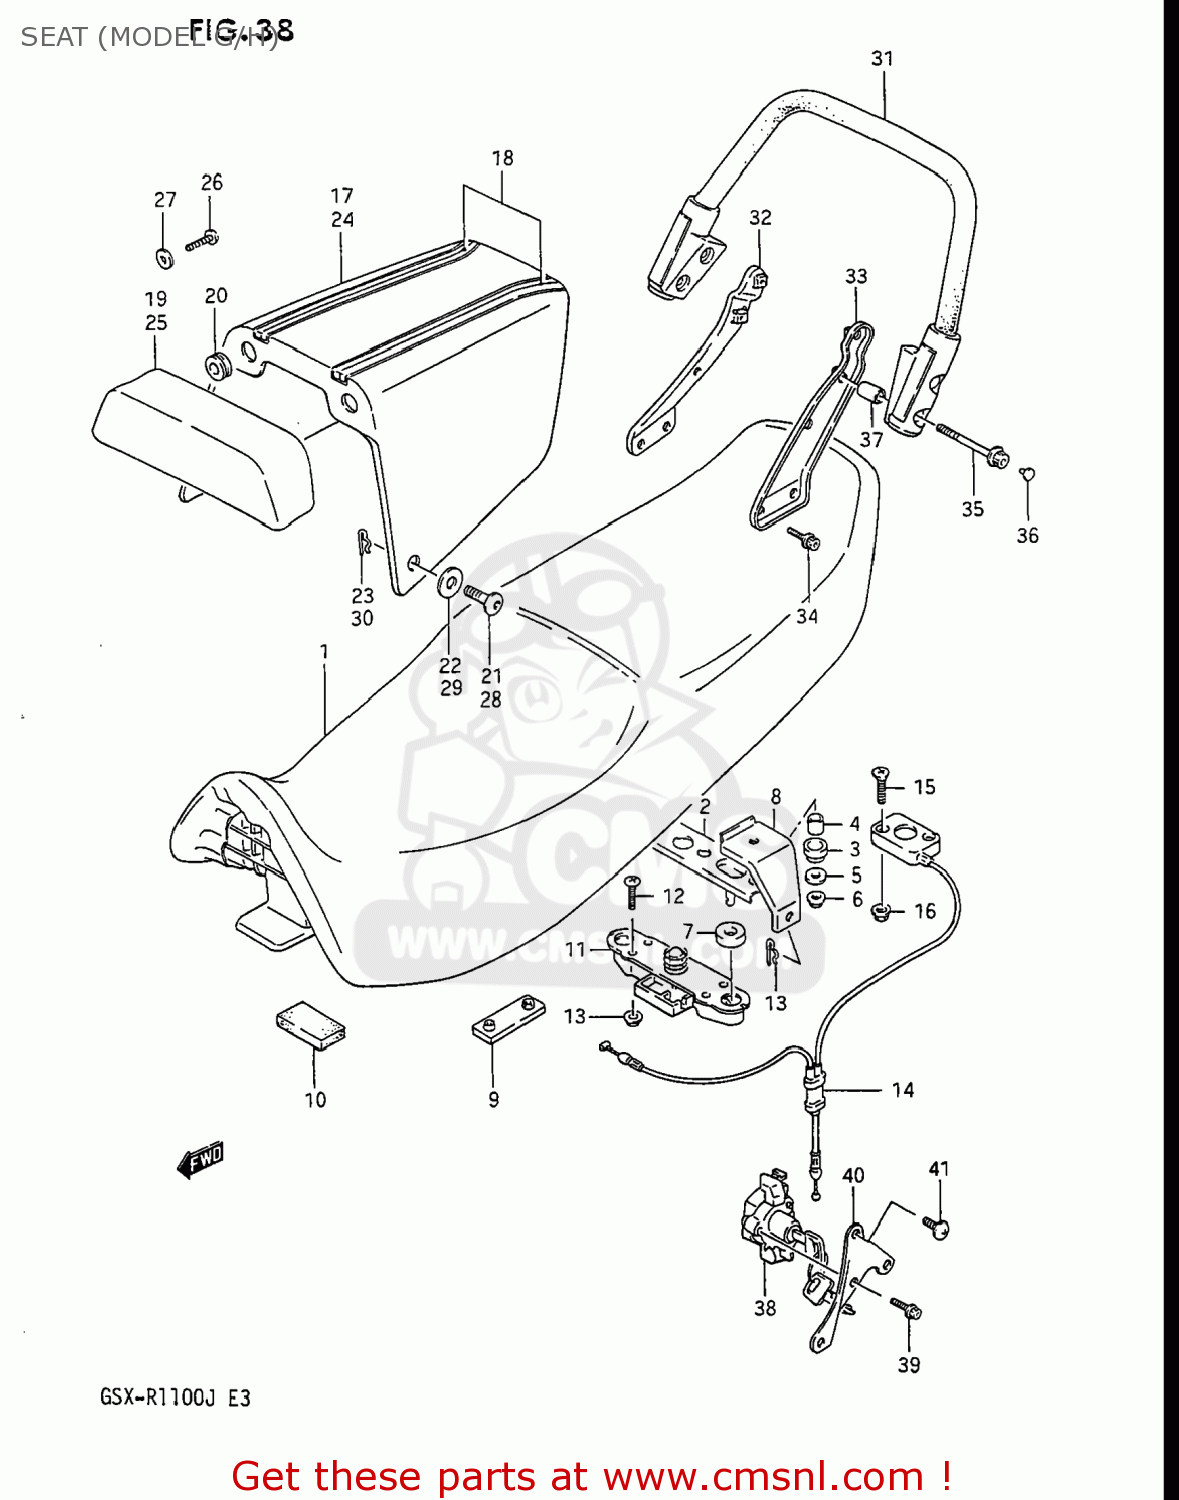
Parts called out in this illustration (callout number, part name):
1	SEAT ASSEMBLY
2	STRIKER,SEAT LOCK
3	CUSHION
4	SPACER
5	WASHER
6	NUT
7	CUSHION
8	PLATE,SEAT GRIP BAND
9	CUSHION
10	CUSHION
11	LOCK ASSY,SEAT STRIKER
12	SCREW
13	NUT
14	BRACKET,SEAT SUPPORT RR
15	SCREW
16	NUT
17	BOX SET,SEAT TAIL
18	TAPE SET,SEAT TAIL BOX
19	BACKREST,SEAT
20	CUSHION
21	BOLT
22	WASHER(10.1X25X3.2)
23	CLIP
24	BOX SET,SEAT TAIL
25	BACKREST,SEAT
26	SCREW, CENTER
27	WASHER (6.5X18X1.6)
28	BOLT
29	WASHER(10X25X3.2)
30	CLIP
31	HANDLE,PILLION RIDER
32	PLATE,PILLION HANDLE,R
33	PLATE COMP,PILLION HANDLE
34	BOLT
35	BOLT
36	CAP(OD:10)
37	SPACER (8.6X13.8X21.5)
38	LOCK SET
39	PLUG ,6X20
40	BRACKET,SEAT LOCK
41	SCREW 6X12
